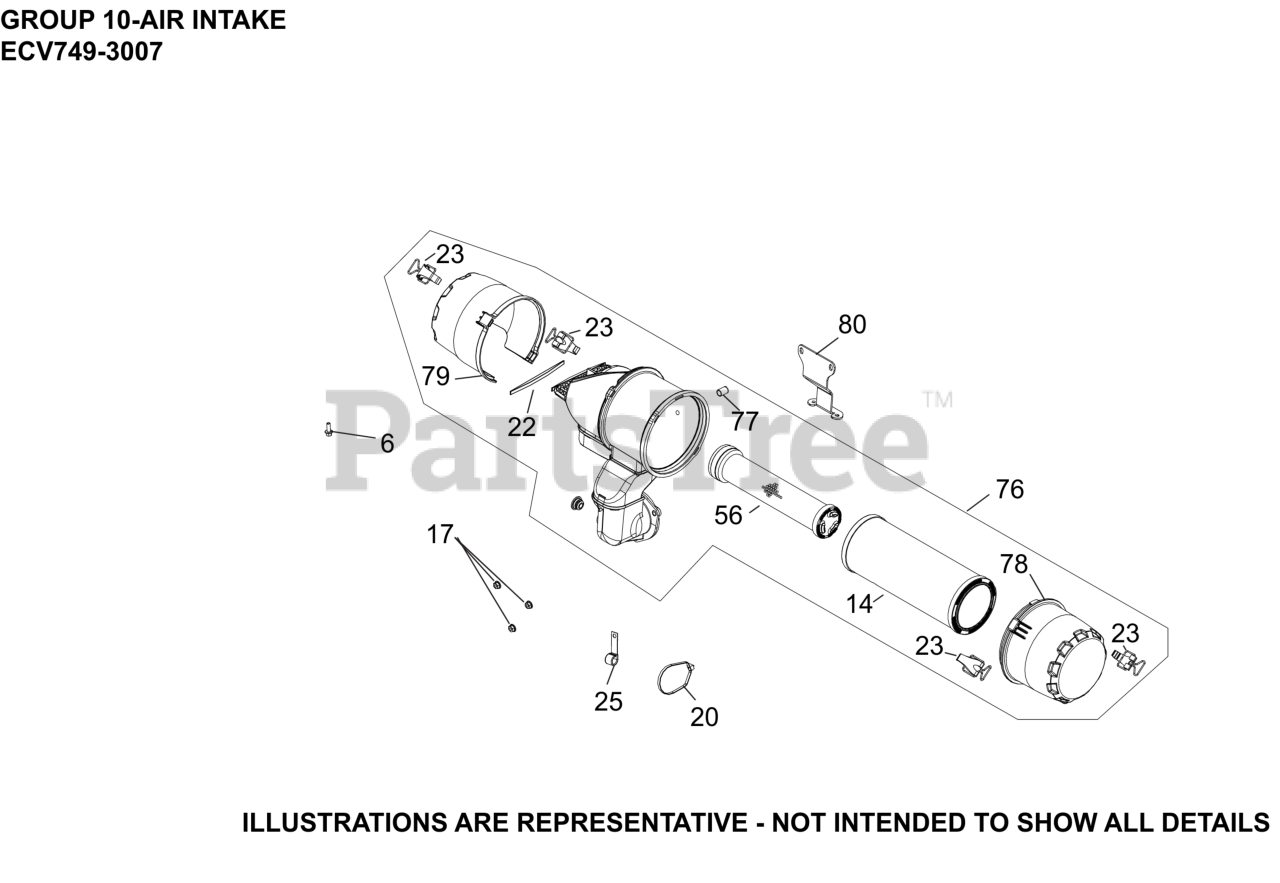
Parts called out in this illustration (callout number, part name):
6	SCREW, FLG M6X1.0X16
14	ELEMENT, AIR FILTER - PRIMARY
17	NUT, FLG M6X1.0
22	DAMPER, FOAM INSERT
23	CLIP ASSEMBLY
25	CLIP, CABLE
56	ELEMENT, AIR FILTER - SAFETY
76	FILTER ASSEMBLY, AIR - OIL FILTER SIDE
77	CAP, MASKING
78	COVER, AIR FILTER
79	COVER, RAIN CAP
80	BRACKET, SUPPORT
